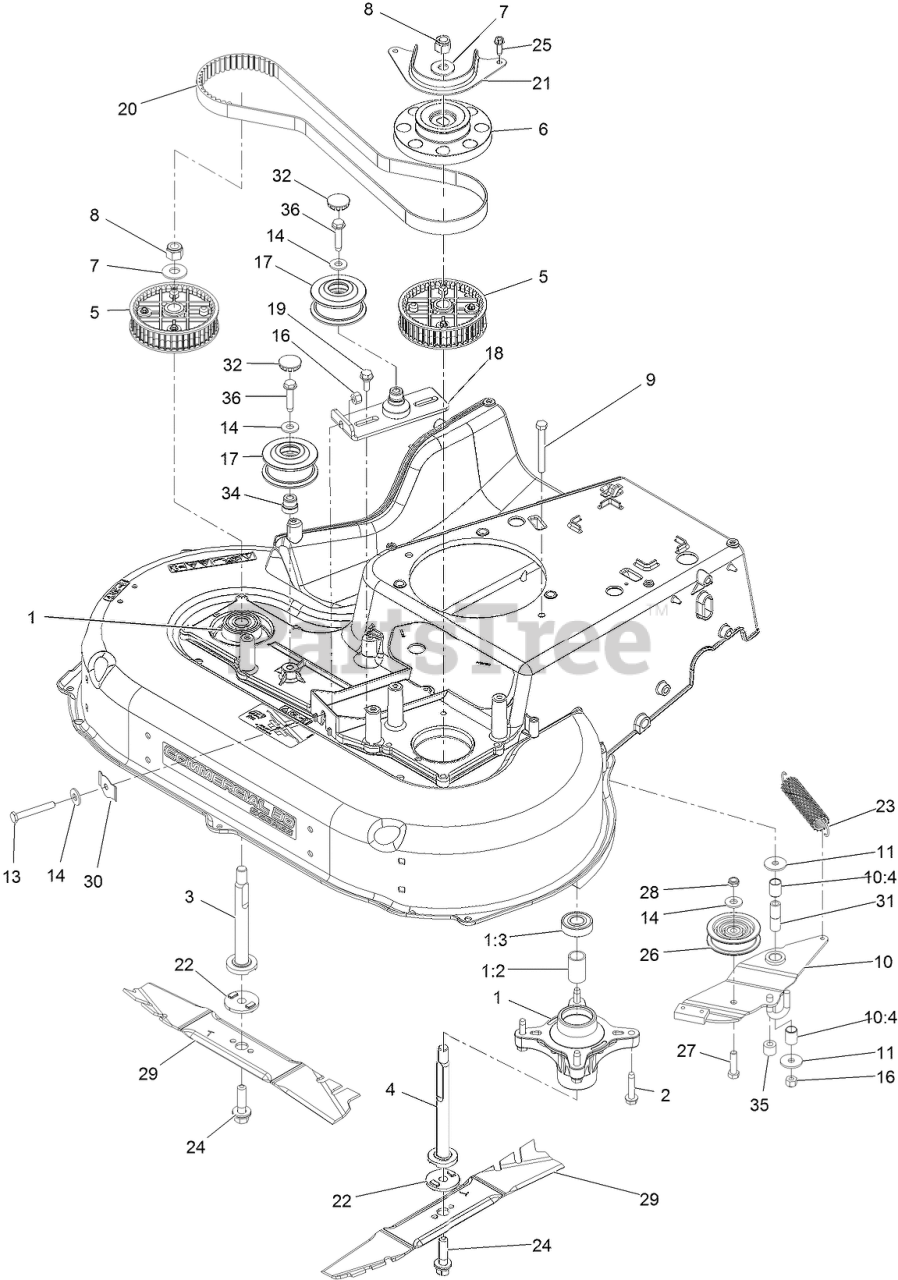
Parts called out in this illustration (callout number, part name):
1	SPINDLE ASM
1:3	BEARING-BALL
2	SCREW-THD ROLL, HWH
3	SHAFT-SPINDLE
4	SHAFT-SPINDLE
5	SPROCKET
6	PULLEY-BRAKE, SPINDLE
7	WASHER-SPRING
8	NUT-HEX
9	SCREW-HH
10	BRAKE ARM ASM
10:4	BUSHING-SLEEVE
11	WASHER-PIVOT
13	BOLT-TAP, HH
14	WASHER-FLAT
16	NUT-LOCK, NI
17	PULLEYS AND IDLER KIT
18	BRACKET-IDLER
19	SCREW-SHOULDER,HWH
20	BELT-SYNCHRONOUS
21	GUIDE-BELT, SPINDLE
22	ADAPTER-BLADE
23	SPRING-EXTENSION, BRAKE
24	BOLT-BLADE
25	SCREW-HWHTF
26	PULLEY-IDLER
27	SCREW-HH
28	NUT-LOCK, NI
29	BLADE-ROTARY
30	SPRING-FLAT
31	SPACER-BRAKE
32	PLUG-BUTTON
34	ADAPTER-BORE
35	HOSE-COOLANT
